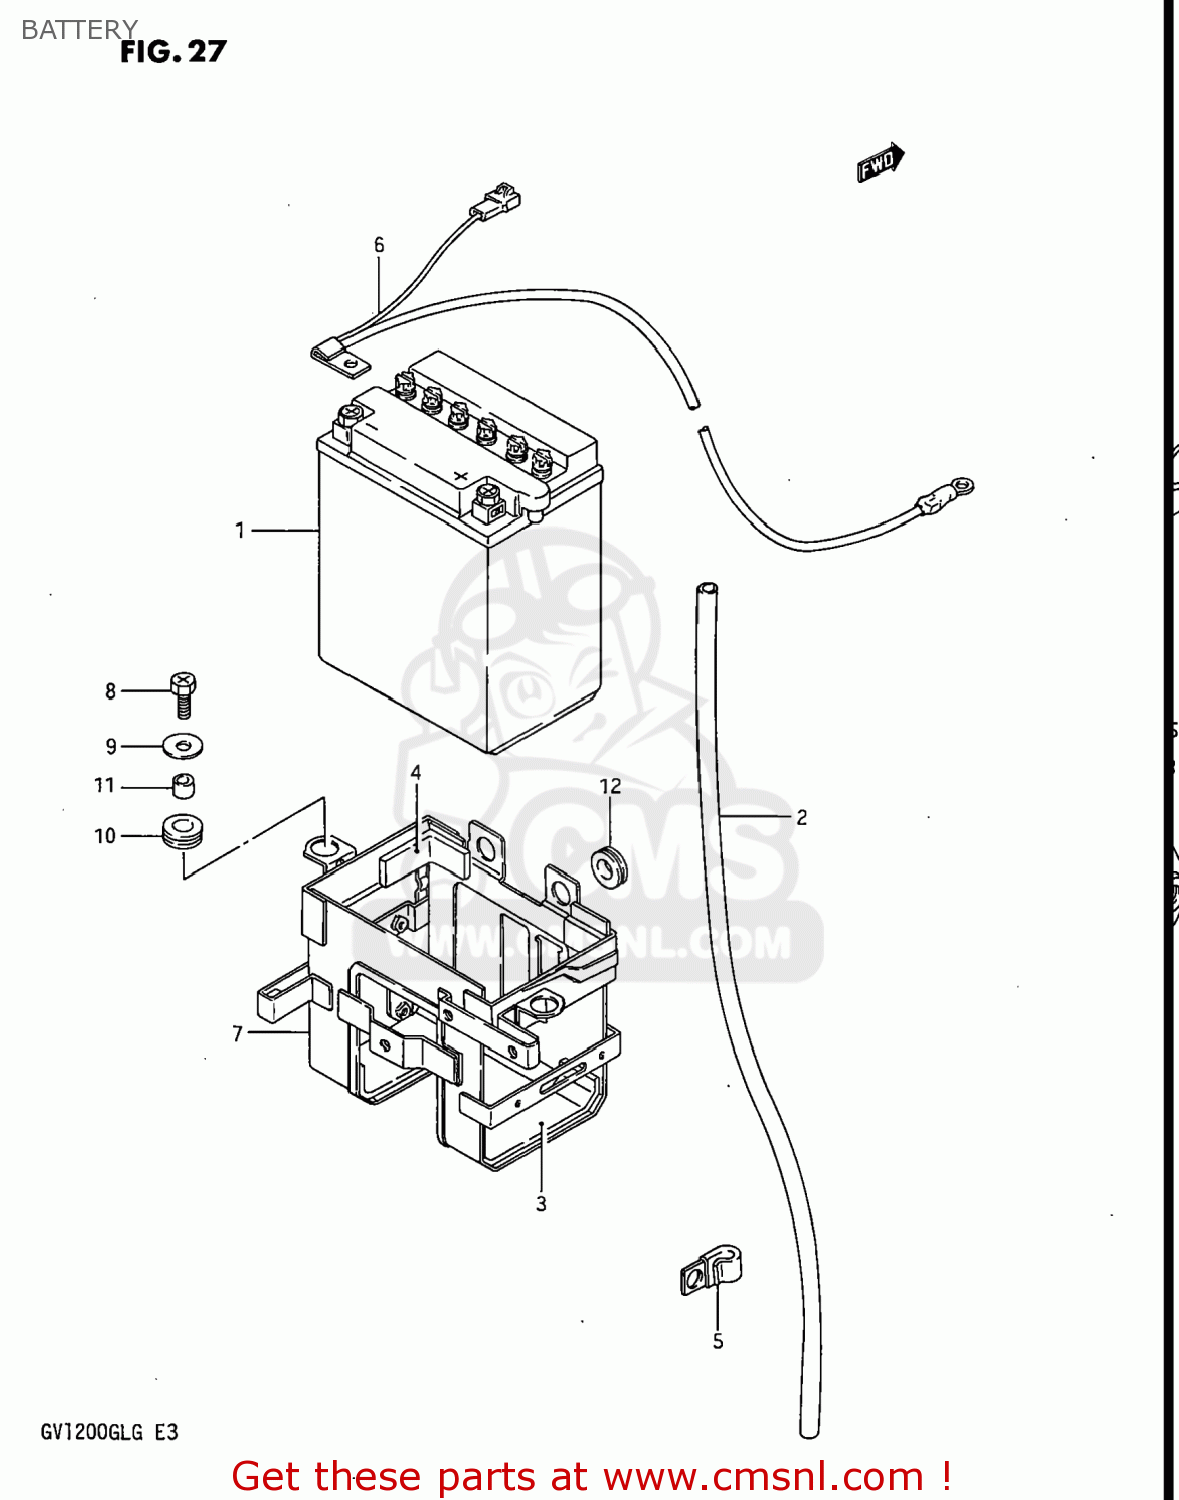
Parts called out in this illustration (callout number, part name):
1	BATTERY ASSEMBLY (12V)
2	HOSE,BATTERY EXHAUST
3	PROTECTOR(170X95X3.0)
4	PROTECTOR,20X9
5	CLAMP
6	WIRE,BATTERY MINUS LEAD
7	HOLDER,BATTERY
8	SCREW
9	WASHER
10	CUSHION
11	SPACER(6.1X9X7.5)
12	GROMMET
